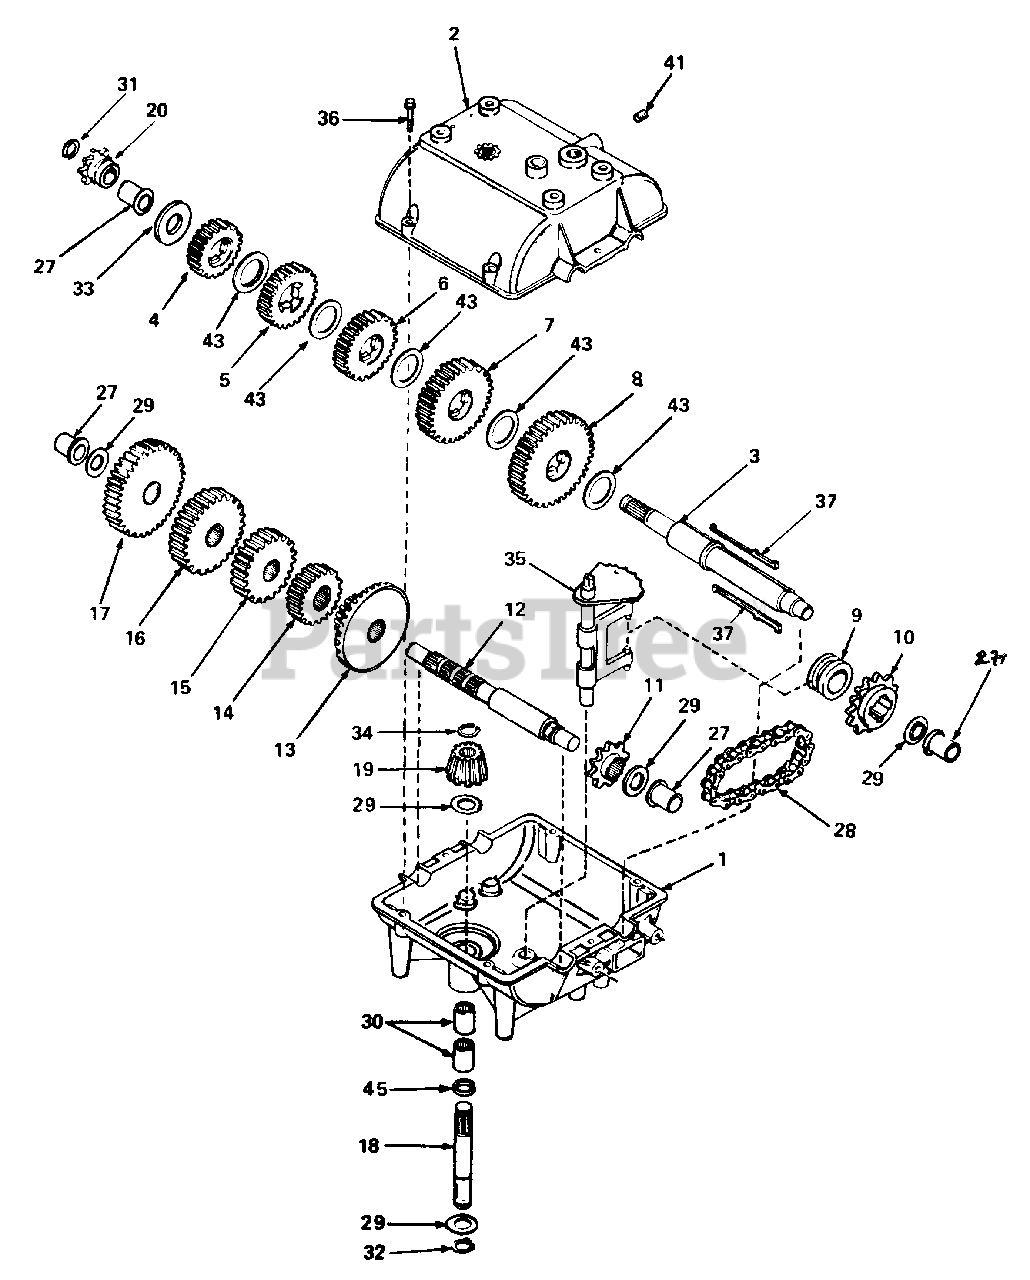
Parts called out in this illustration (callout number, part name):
1	CASE, TRANSMISSION
2	COVER, TRANSMISSION
3	SHAFT, OUTPUT
4	GEAR, SPUR (20 TEETH)
5	GEAR, SPUR (22 TEETH)
6	GEAR, SPUR (25 TEETH)
7	GEAR, SPUR (30 TEETH)
8	GEAR, SPUR (35 TEETH)
9	COLLAR, SHIFT
10	SPROCKET (18 TEETH)
11	SPROCKET (9 TEETH)
12	SHAFT, COUNTER
13	GEAR, BEVEL (42 TEETH AND 15 TOOTH SPUR GEAR)
14	GEAR, SPUR (20 TEETH)
15	GEAR, SPUR (25 TEETH)
16	GEAR, SPUR (28 TEETH)
17	GEAR, SPUR (30 TEETH)
18	SHAFT, INPUT
19	BEVEL PINION, INPUT
20	SPROCKET (8 TEETH)
27	BUSHING, FLANGED
28	CHAIN, ROLLER (NO. 41 CHAIN, 24 LINKS)
29	RACE, THRUST
30	BEARING, NEEDLE
31	RING, RETAINING
32	RING, RETAINING
34	RING, RETAINING
35	ROD & FORK ASSY., SHIFT
36	SCREW, HEX HD. TAP-TITE, 1/4-20X1-1/4
41	SCREW, SET 3/8-16X3/8
43	WASHER, THRUST
